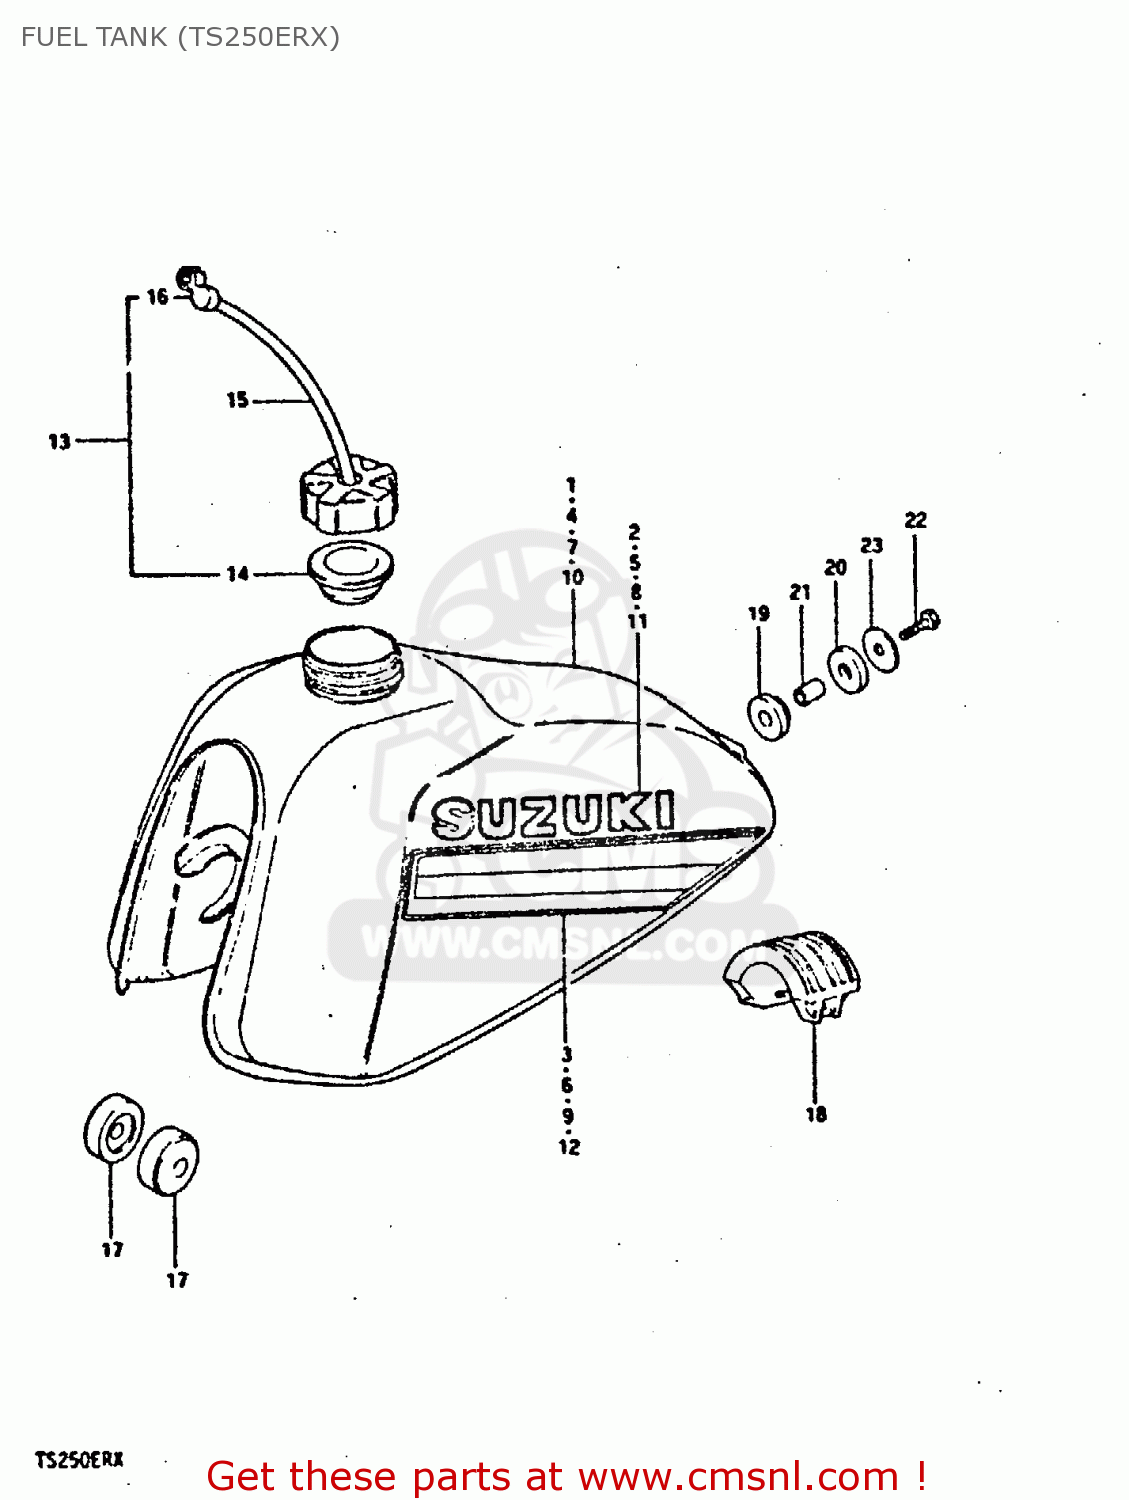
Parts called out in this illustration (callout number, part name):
1	TANK, FUEL (BLUE)
2	EMBLEM
3	TAPE SET
4	TANK, FUEL (RED)
5	EMBLEM
6	TAPE SET
7	TANK, FUEL (YELLOW)
8	EMBLEM(BLACK)
9	TAPE SET
10	TANK, FUEL (WHITE)
11	EMBLEM(BLACK)
12	TAPE SET
13	CAP SET,FUEL TANK
14	GASKET,FUEL TANK CAP (NAS)
15	HOSE
16	CLAMP,FUEL TANK BREATHER HOSE
17	CUSHION
18	CUSHION,FUEL TANK
19	CUSHION
20	CUSHION
21	SPACER (8.2X12X17)
22	BOLT (8X30)
23	WASHER (8.5X29X1.6)
